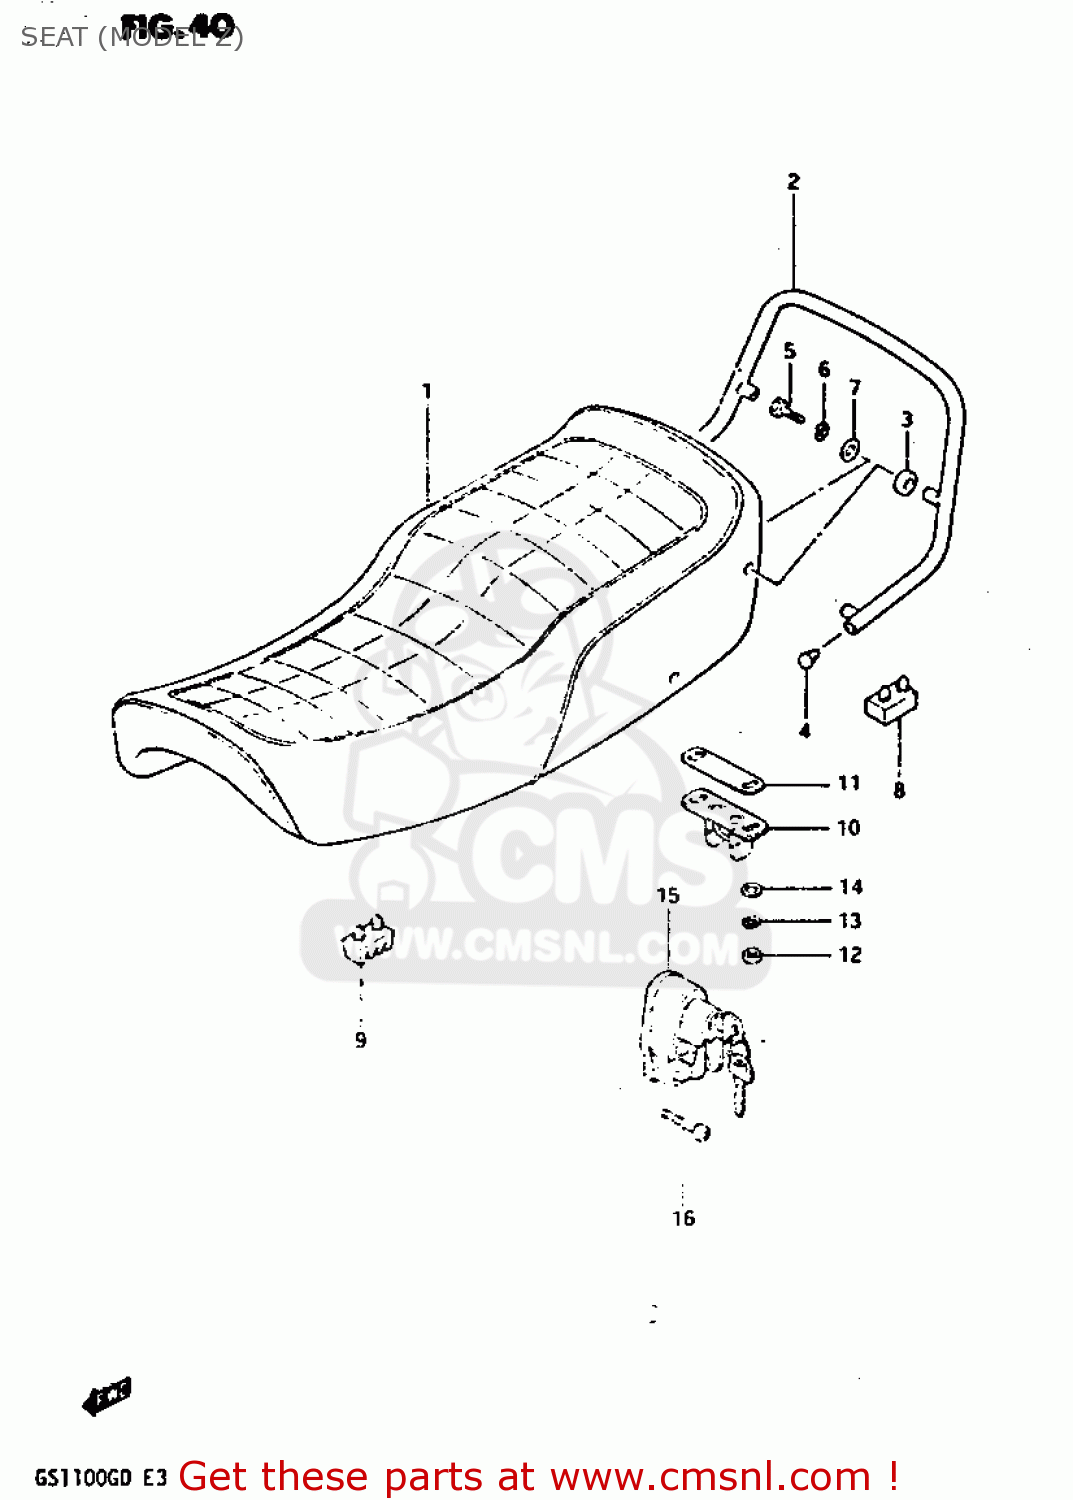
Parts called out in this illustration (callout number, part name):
1	SEAT ASSEMBLY
2	HANDLE,PILLION RIDER
3	CUSHION
4	END,SHEET HANDLE
5	BOLT
6	LOCK WASHER
7	WASHER
8	CUSHION(40X23X12.7)
9	CUSHION,SUPPORT(50X25X32)
10	STRIKER,SEAT LOCK
11	SHIM,SEAT LOCK STRIKER
12	NUT 6MM
13	WASHER,LOCK
14	WASHER
15	LOCK ASSY,HELMET
16	BOLT
